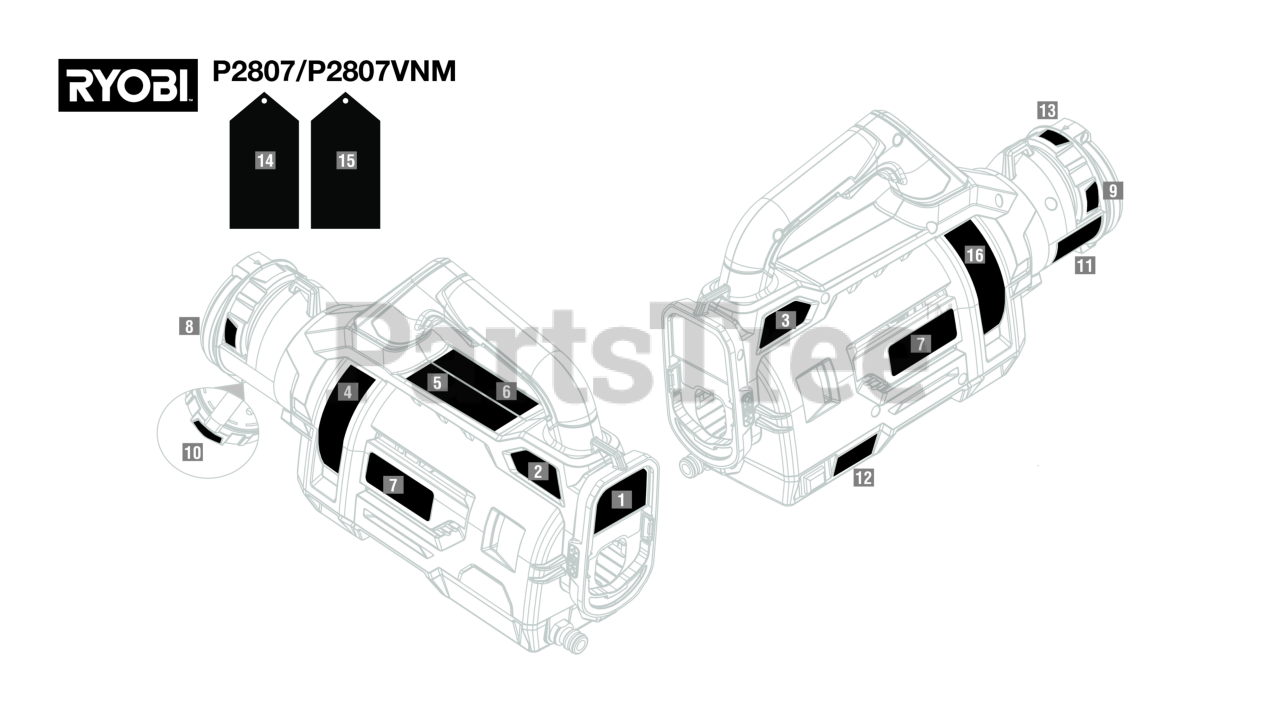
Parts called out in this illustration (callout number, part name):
1	Data Label
2	18V Label (Left)
3	18V Label (Right)
4	Electrostatic Logo Label (Left)
5	Warning/Icon Label
6	Warning Label
7	Logo Label
8	High Spray Nozzle Label
9	Low Spray Nozzle Label
10	Medium Spray Nozzle Label
11	Caution Label
12	ES On/Off Label
13	Remove/Eject Puck Label
14	Cleaning Nozzle Reference Guide Hang Tag (EN/FR/SP)
15	Cleaning Nozzle Reference Guide Hang Tag (PORT)
16	Electrostatic Logo Label (Right)
